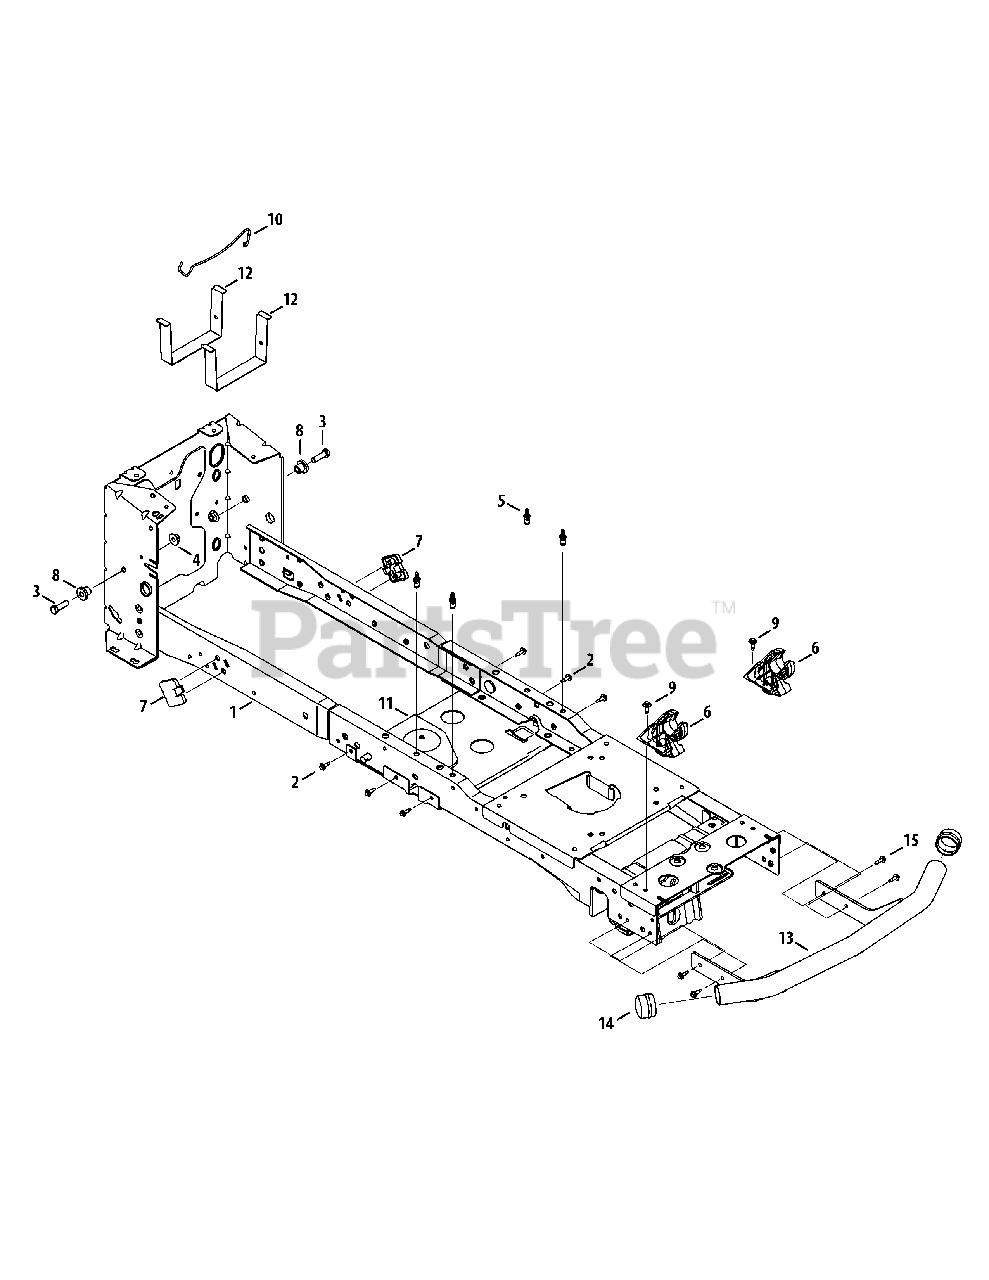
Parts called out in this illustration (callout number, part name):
1	Frame Assembly
2	Screw, M6-1 x .625
3	Hex Cap Screw, 3/8-16 x 1.25
4	Flange Lock Nut, 3/8-16
5	Rivet, 1/4-20 x .750
6	Pivot Bracket
7	Wear Pad
8	Shoulder Spacer, .38 x 1.0 x .70
9	Shoulder Screw, M6-1
10	Rod, Battery
12	Battery Bracket
13	Bumper Assembly (Black)
13	Bumper Assembly (Yellow)
14	Bumper Cap
15	Hex Flange Screw, 3/8-16
